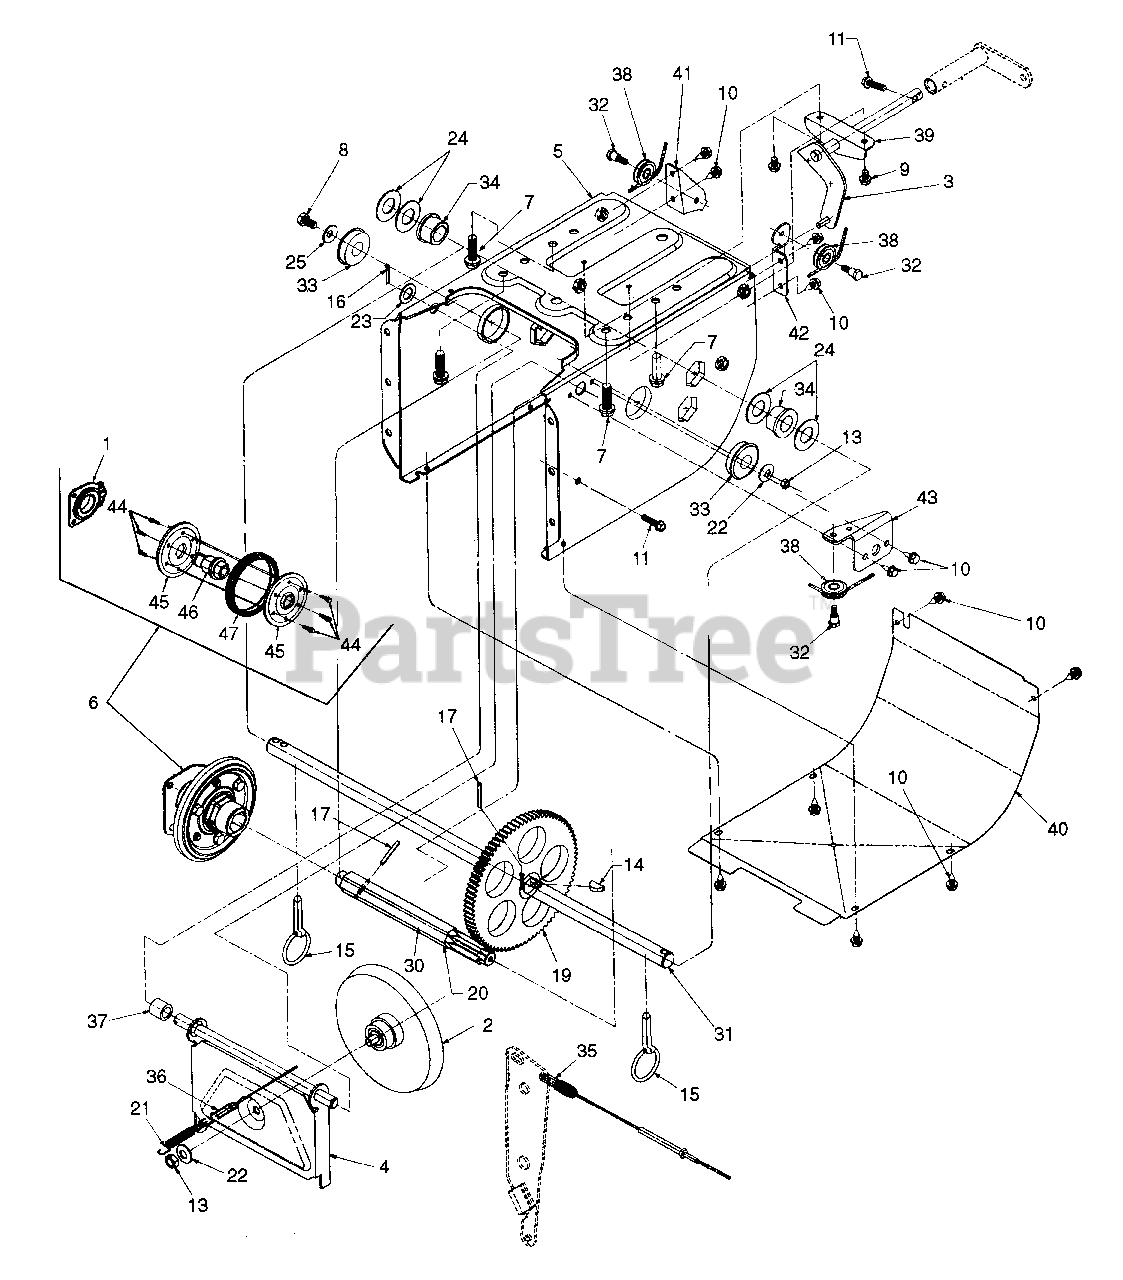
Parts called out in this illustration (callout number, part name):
1	Bearing Ass'y, Friction Wheel
2	Friction Disc Ass'y
7	Screw, Hex Wash Hd Tapp 3/8-16 x 1.0
8	Screw, Hex Cap, 5/16-18 x .75
9	Screw, Hex Wash Hd Tapp 1/4-20 x .50
10	Screw, Hex Wash Hd Tapp 1/4-014 x .625
11	Screw, Hex Wash Hd Tapp 1/4-20 x 1.
13	Nut, Hex Jam, 3/8-24
14	Key, Hi Pro, 3/16 x 3/4
15	Pin, Klick
16	in, Cotter
17	Pin, Roll, .156 x 1.125
19	Gear, 80T
20	Shaft, Hex, 7T
21	Extension Spring
22	Washer, Bell, .401 x .87 x .063
23	Washer, Flat, .536 x .93 x .05
24	Washer, Flat, .76 x 1.49 x .06 Hdn
25	Washer, Bell, .345 x .88 x .06
30	Lubricant
31	Axle, 13" Wheel (522E)
32	Screw, Shoulder
33	Bearing, Ball
34	Bearing, Flange
35	Cable, Auger Clutch
36	Cable, Drive Clutch
37	Spacer, .508 x .75 x .68
38	Roller, Cable
45	Friction Plate
46	Friction Wheel Hub
47	Friction Wheel Rubber
